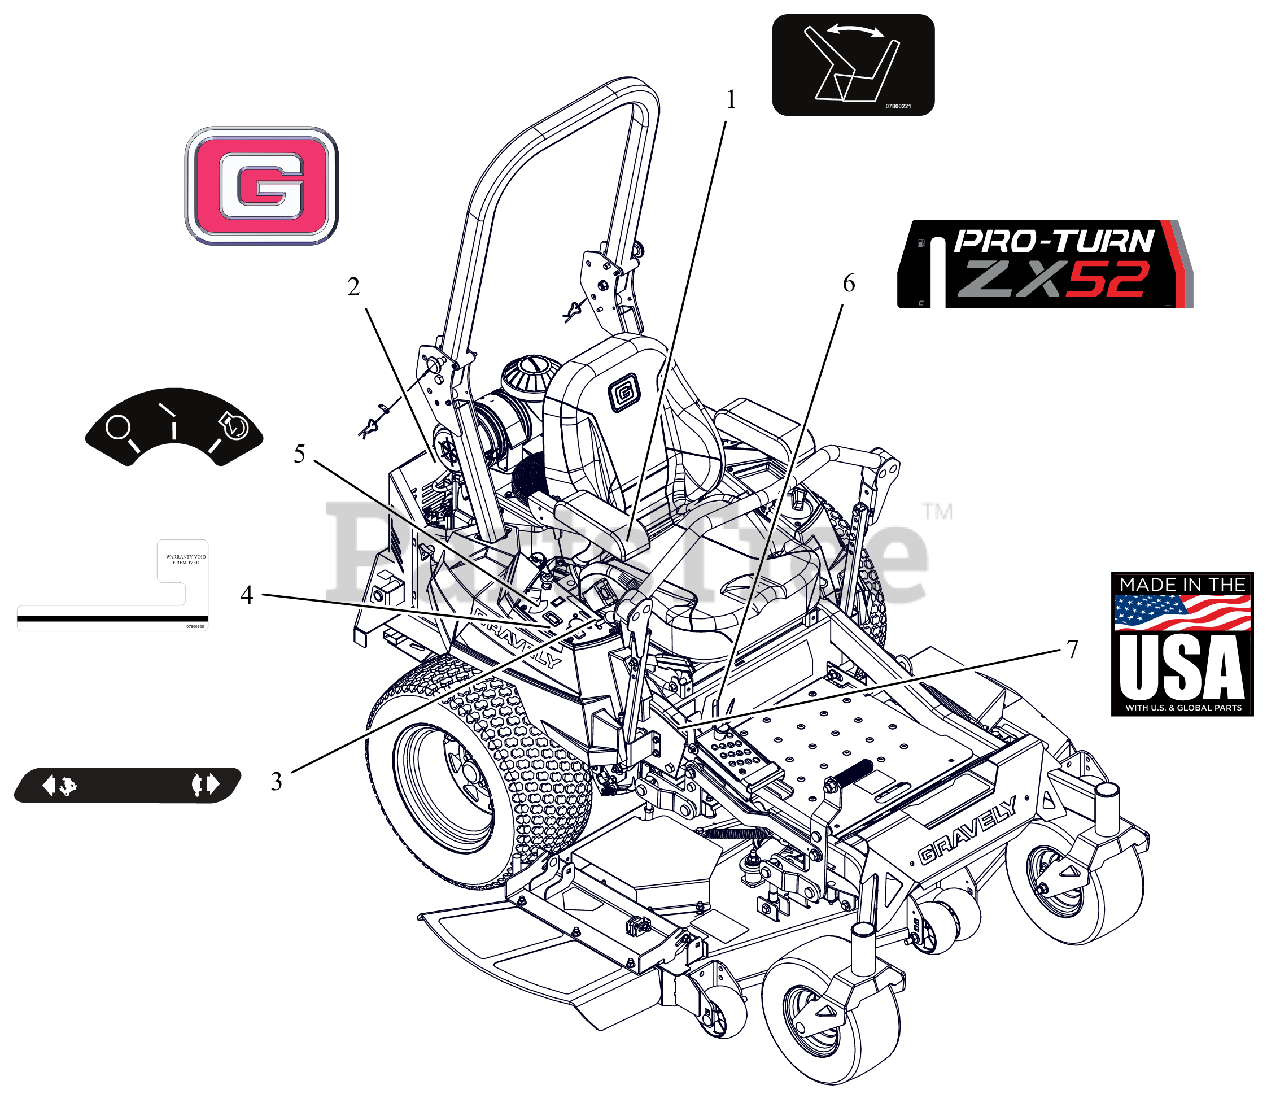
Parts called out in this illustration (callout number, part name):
1	DECAL - SEAT RELEASE
2	DECAL, GRAVELY BRAND
3	DECAL, DASH DECAL
4	DECAL,HOURMETER - SECURITY
5	DECAL, KEYSWITCH
6	DECAL, PROTURN ZX 52
7	DECAL, MADE IN USA
